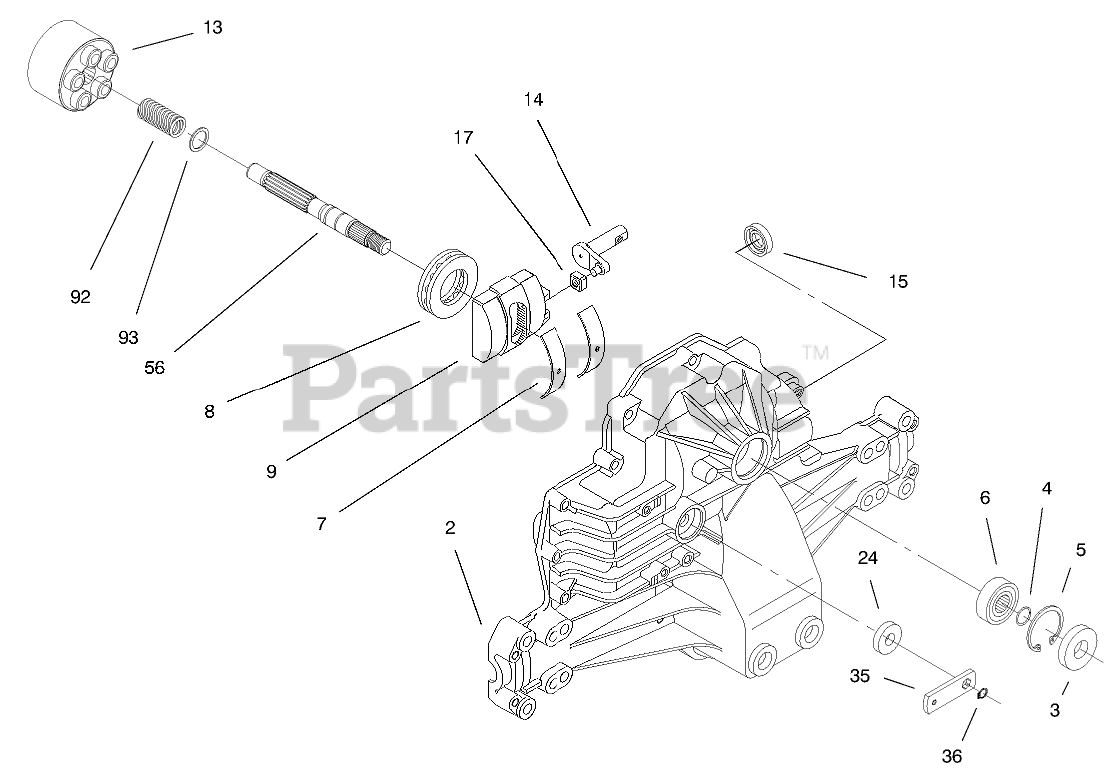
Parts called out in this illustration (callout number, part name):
2	ASM - HOUSING UPPER
3	SEAL-LIP
4	RING-WIRE, RETAINING
5	RING-RETAINING
6	BEARING-SHAFT, BALL
7	BEARING-CRADLE
8	BEARING-THRUST
9	SWASHPLATE-VARIABLE
13	BLOCK - CYCLINDER ASM
14	ARM-TRUNION
15	SEAL-LIP
17	GUIDE-SLOT
24	SEAL-LIP
35	ARM - BYPASS
36	RING-RETAINING
56	SHAFT - INPUT
92	SPRING-BLOCK
93	WASHER-THRUST
